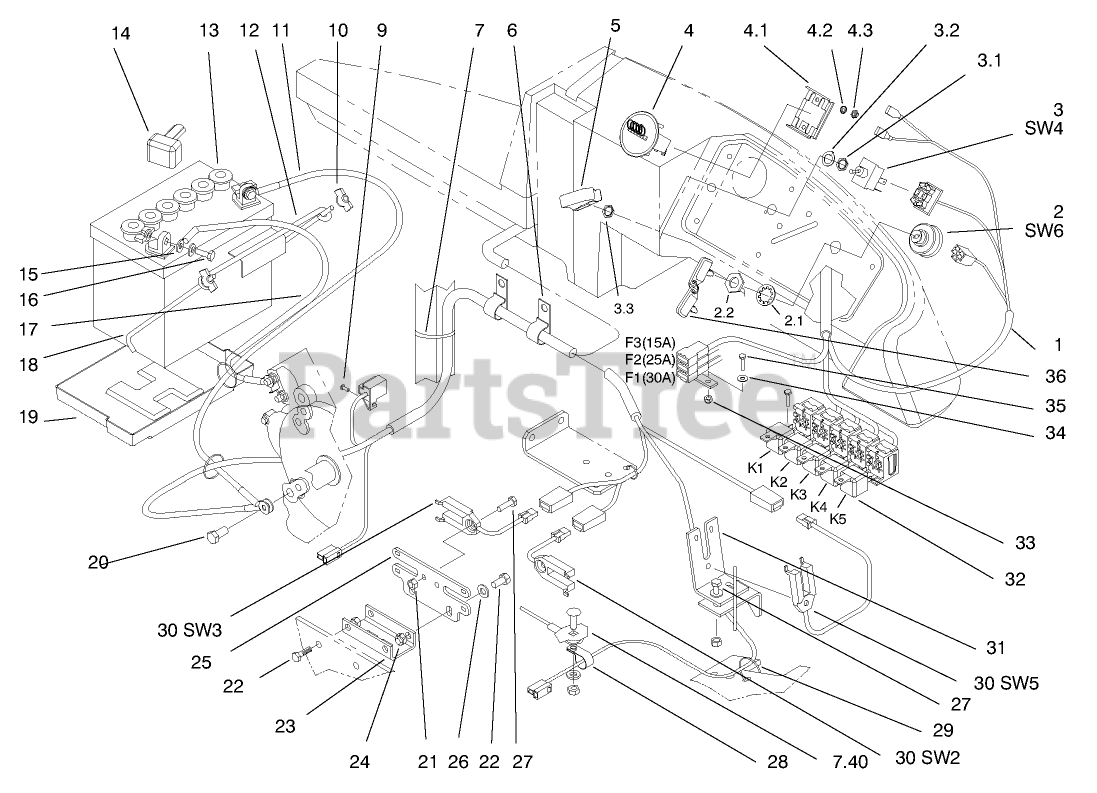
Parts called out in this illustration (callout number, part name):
1	Harness-Main
2	IGNITION SWITCH ASM
2.2	WASHER-LOCK
3	SWITCH-TOGGLE, SEALED
3.1	NUT-HEX, SPECIAL
3.2	TAB-WASHER
4	Hourmeter
4.1	CLAMP-HOUR METER
4.2	WASHER-LOCK
4.3	NUT-HEX
5	COVER-PTO SWITCH
6	CLAMP-J
7	TIE-CABLE
9	SCREW-TAP
10	NUT-WING
11	WIRE ASM (NEGATIVE)
12	HOLDDOWN-BATTERY
13	Battery
14	BOOT-TERMINAL
15	WASHER-FLAT
16	SCREW-HH
17	WIRE ASM
18	RETAINER-BATTERY
19	TRAY-BATTERY
20	SCREW-HH
21	NUT-LOCK, NI
22	SCREW-HH
23	CHANNEL-MOUNT, SWITCH
24	NUT-LOCK, NI
25	PLATE-MOUNT, SWITCH
26	WASHER-PLAIN
27	SCREW-HH
28	CLAMP-R
29	TIE-CABLE
30	SWITCH-INTERRUPTER
31	ANGLE - MOUNT,SWITCH
32	RELAY
33	NUT-LOCK, NI
34	WASHER-FLAT
35	SCREW-HWH
36	KEY-IGNITION
